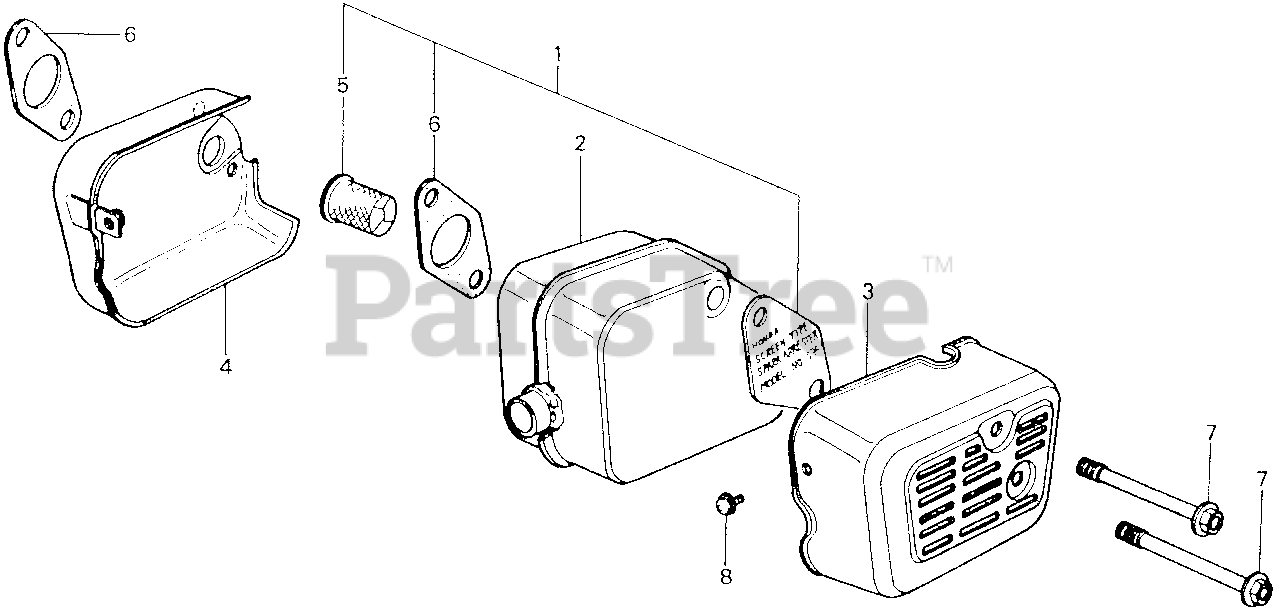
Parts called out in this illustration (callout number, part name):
1	ARRESTER KIT, SPARK
3	PROTECTOR, MUFFLER
4	SEPARATOR, MUFFLER (NOT AVAILABLE)
5	ARRESTER KIT, SPARK
6	GASKET, MUFFLER
7	BOLT, FLANGE (8X100)
8	SCREW-WASHER (5X10)
